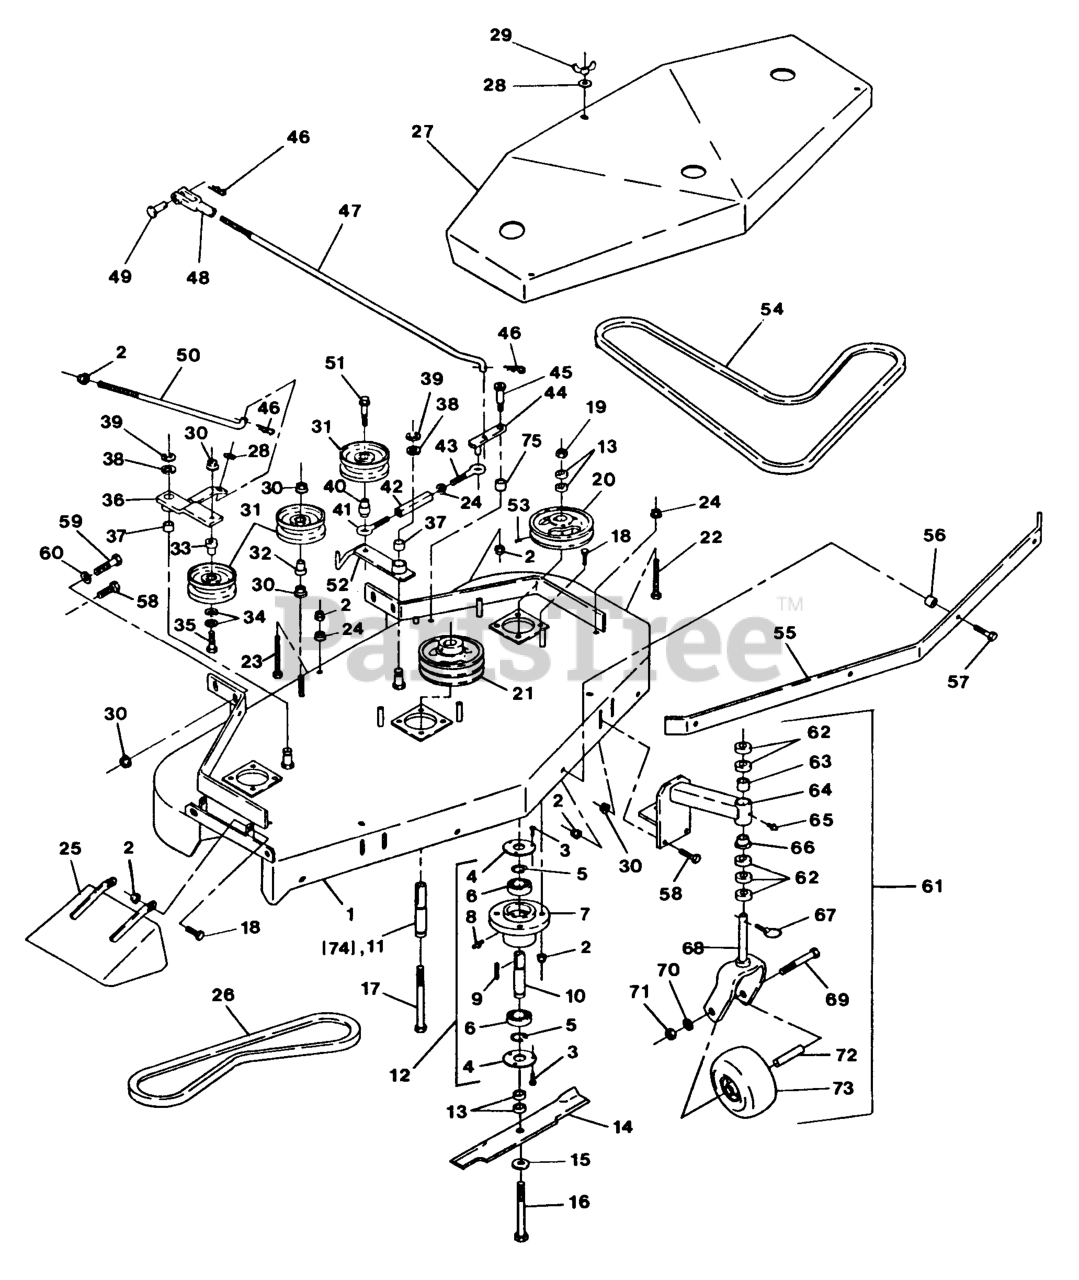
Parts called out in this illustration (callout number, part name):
3	SCRWMACH PHS
7	HOUSING,CUTTER
10	SPINDLE,CUTTER
12	HOUSING,CUTTER COMPLETE
17	SCREW-CAP, HH
20	PULLEY,CAST IRON
22	BOLT,TAP HH
23	BOLTTAP HH
26	BELT,FRONT DECK
31	IDLER,PULLEY
33	BUSHING-IDLER
36	ARM,IDLER COMPLETE
37	BEARING,POWDERED METAL
38	WASHER-SPINDLE
40	BUSHING-ENGAGEMENT
41	EYEBOLT-THREAD, LH
42	BODY-TURNBUCKLE
43	EYEBOLT-THREAD, RH
45	BOLT,SHLDR KSKH
46	PIN-COTTER
48	YOKE-ADJUSTABLE
49	PIN-CLEVIS
50	ROD,BELT TENSION
53	SCREW-SET
54	BELT,MAIN DECK
62	SPACER-CASTER
63	BEARING,STRAIGHT
74	HOUSING,CUTTER COMPLETE
